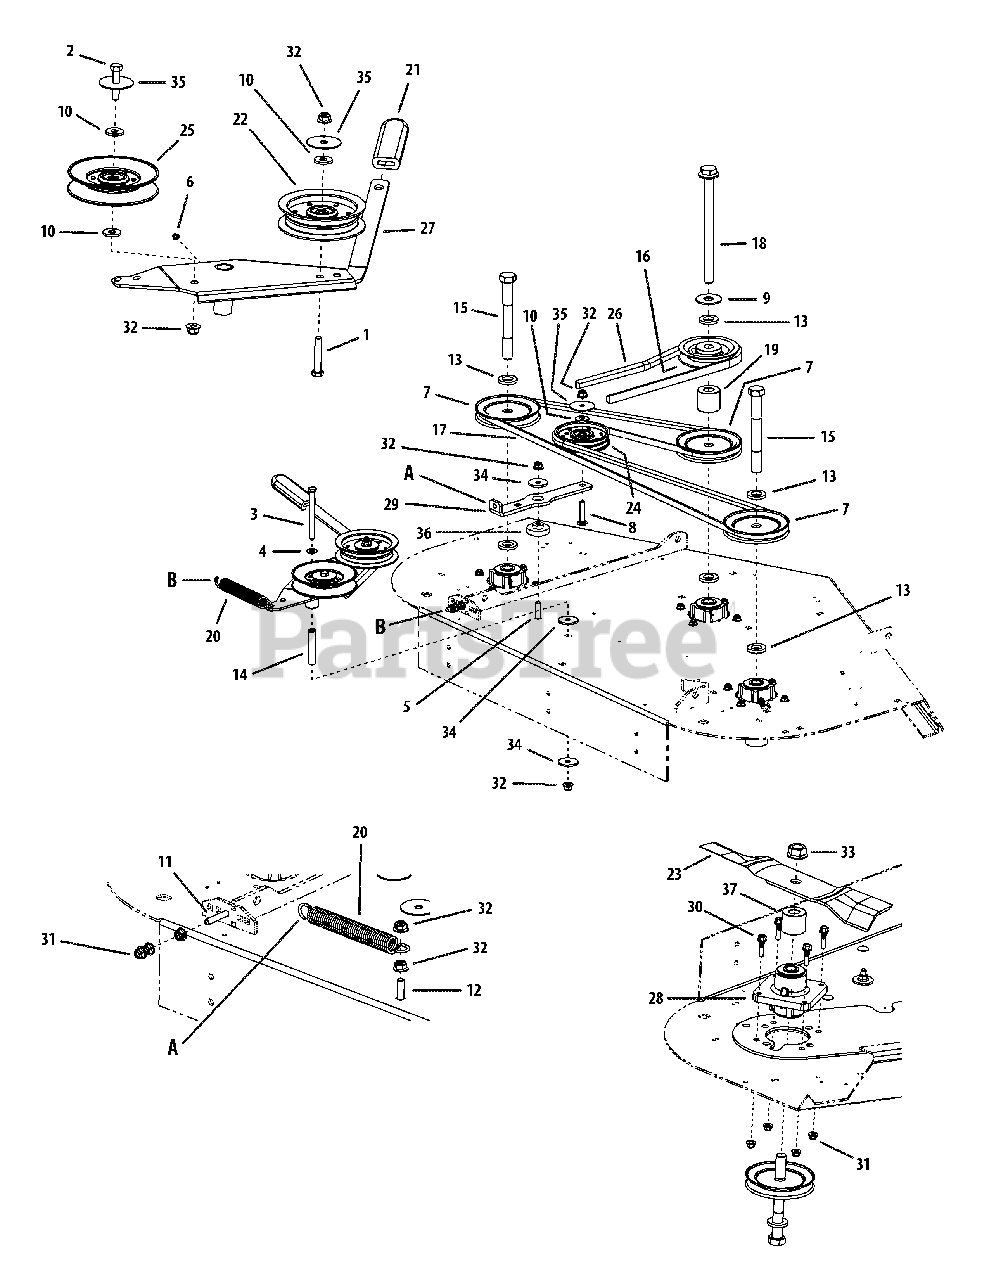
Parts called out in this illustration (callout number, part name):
1	Hex Cap Screw, 3/8-16 x 2.00
2	Hex Cap Screw, 3/8-16 x 1-3/4
3	Hex Cap Screw, 3/8-16, 4.00
4	Washer, 3/8
5	Carriage Bolt, 3/8-16 x 1-1/2
6	Grease Fitting, 1/4-28 x 3/16
7	V-Pulley 4.90 OD, Deck
8	Carriage Bolt, 3/8-16, 1.75
9	Flat Washer, .781 ID 2.00 OD, .105
10	Flat Washer, .406 ID, 1.0 OD, .105
11	Carriage Bolt, 5/16-18 x 1.75
12	Carriage Bolt, 3/8-16 x 1.25
13	Spacer .812 ID x .268 LG
14	Spacer, .39 ID x .625 OD x 2.75
15	Hex Cap Screw, 3/4-16 x 6.50
16	V-Pulley 4.75 OD
17	V-Belt, A Section x 105.3
18	Hex Cap Screw, 3/4-16, 9.00
19	Spacer, .76 ID x 1.75 OD x 1.60
20	Extension Spring, .94 OD x 7.57 LG
21	Idler Tension Handle Grip
22	Idler Pulley, 4.06 OD w/Deep Flange
23	Blade, 17.0, Hi-Lift, 0.756 ID
24	Idler Pulley, 4.06 Dia.
25	Idler Pulley, 5.06 Dia.
26	V-Belt, B Section, 86.2, PTO
27	Idler Arm Assembly includes:
27	Bearing
28	Aluminum Spindle Assembly
30	Bolt, 5/16-18 x 1.25
31	Nut, Nylon Insert, 5/16-18
32	Nut, Nylon Insert, 3/8-16
33	Nut, 3/4-16, Flangelock
34	Washer, .390 x 1.50 x .134
35	Washer, .406 x 1.92 x .060
36	Shoulder Spacer, .854 x .280
37	Spacer, .76 ID x 1.75 OD x 1.50
